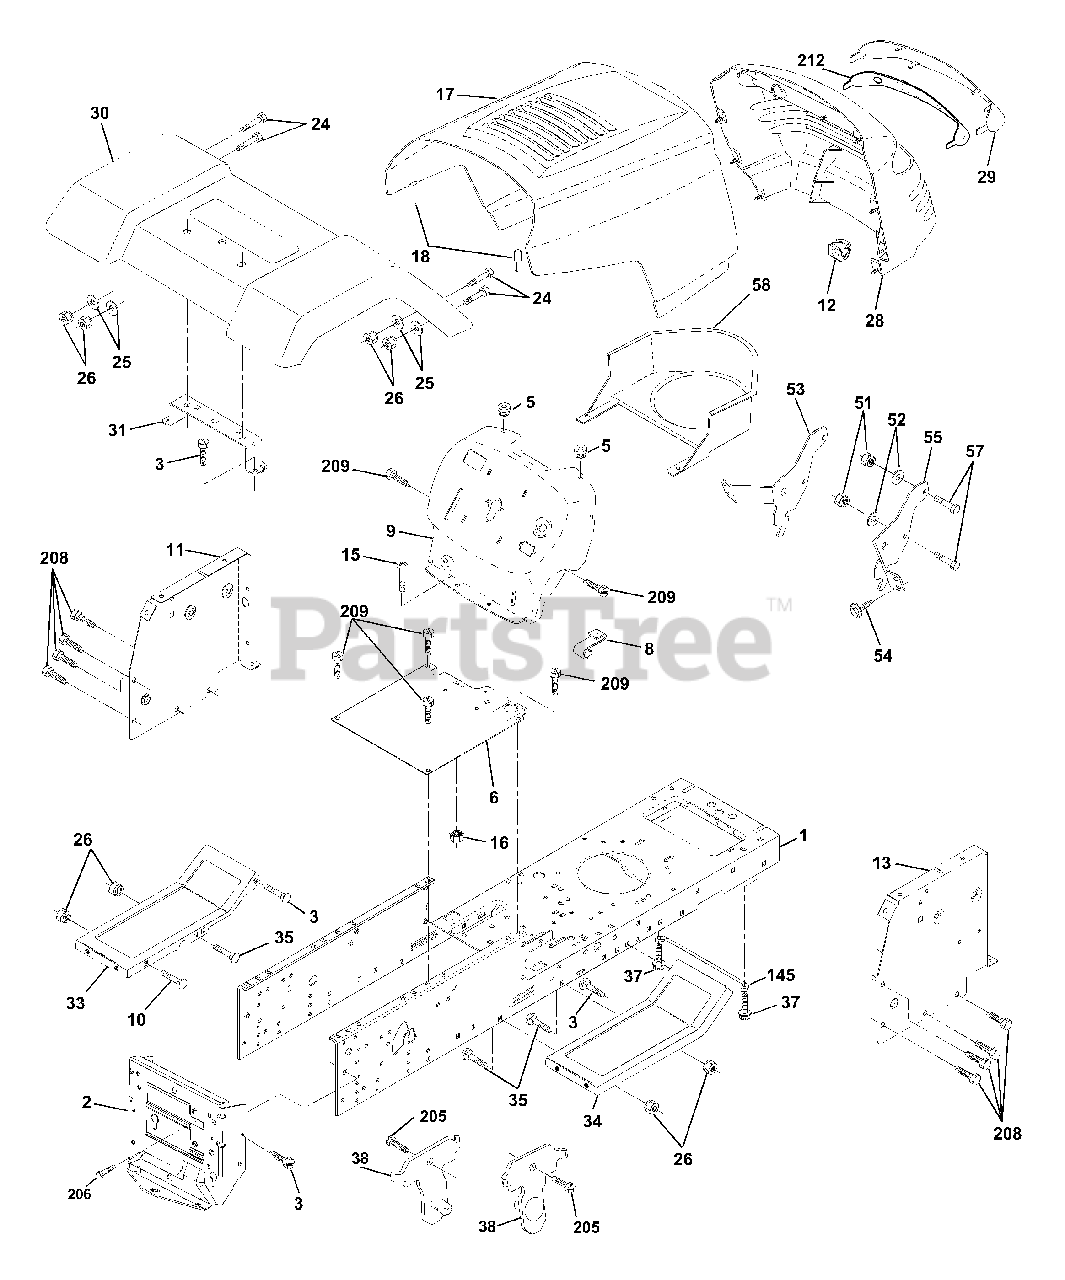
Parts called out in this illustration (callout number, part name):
3	Screw 3/8-16 x 3/4
5	Bumper, Hood/Dash
8	Clip Retainer Slide-On
10	Bolt, Carriage 3/8-16 x 1
11	Panel Dash LH
12	Clip Tinnerman Grille P.L
13	Panel Slkscr Dash RH
15	Screw Mach TRHD 5/16-18uncx3/4
16	Nut Keps 5/16-18 Unc
17	Hood
18	Bumper Hood
24	Bolt Fin Hex 3/8-16unc X 1 Gr. 5
25	Washer 13/32 X 13/16 X 12 Ga
26	Nut Lock Hex w/Ins 3/8-16 Unc
28	Grille/Lens Asm.
29	Lens Grille Private Label
30	Fender
31	Bracket Fender Repl 109873x
33	Footrest Pnt LH Perf
34	Footrest Pnt RH Perf
35	Bolt Rdhd Sht Sqnk 3/8-16 X3/4
37	Screw Thdrol 5/16-18 x 1/2 TYT
38	Bracket Asm. Pivot Mower Rear
51	Nut Lock W/Insert 1/4-20unc
52	Washer 9/32 x 7/8x16 Ga.
53	Bracket Grille Lh
54	Screw Hex 8-18 x 7/8
55	Bracket Grille Rh
57	Bolt Fin Hex 1/4-20 unc x .75
58	Duct Air Engine PL/LT
145	Rod Pivot Chassis/Hood
205	Screw Thdrol 3/8-16 x 1/2
206	Bolt Shoulder 5/16-18
208	Screw Thdrol 3/8-16 x 1/2
209	Screw Hex Wsh Thdrol 3/8-16
212	Insert Lens Reflect
